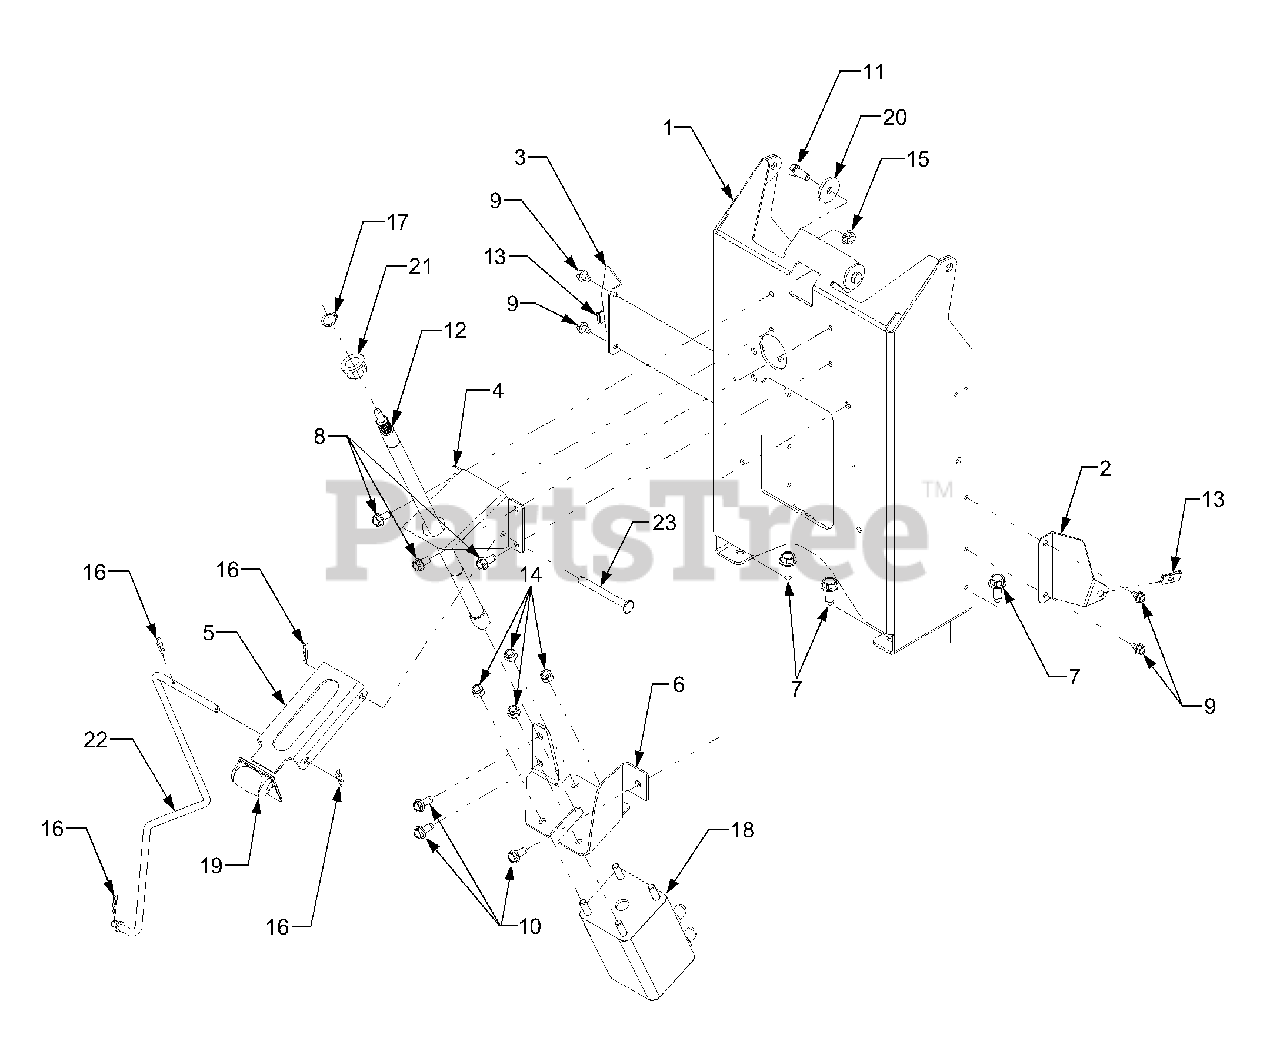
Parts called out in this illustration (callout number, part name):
1	Pedestal
2	Bracket, Dash Mtg. RH
3	Bracket, Dash Mtg. LH
4	Bracket, Steering Column
5	Bracket, Brake Lever
6	Bracket, Pump Mtg
7	Screw, Hex Wash, Hd Tapp 3/8-16 x .75
8	Screw, Hex Wash, Hd Tapp 1/4-20 x .75
9	Screw, Hex Wash, Hd Tapp 1/4-20 x .375
10	Screw, Hex Wash, Hd Tapp 5/16-18 x .75
11	Screw, Hex Cap 5/16-18 x .75 GR5
12	Shaft, Steering
13	Nut, Speed, 1/4-20
14	Nut, Hex Nylon Insert Lock, 5/16-24 GR8
15	Nut, Hex Flange Lock, 5/16-18
16	Pin, Internal Cotter
17	Ring, Snap, .75 ID.
18	Pump, Hydraulic Steering
19	Lever, Parking Brake
20	Washer, Flat, .33 x 1.25 x .12
21	Bearing, Hex Flange, .75 ID
22	Rod, Parking Brake
23	Pin, Parking Brake Pivot
